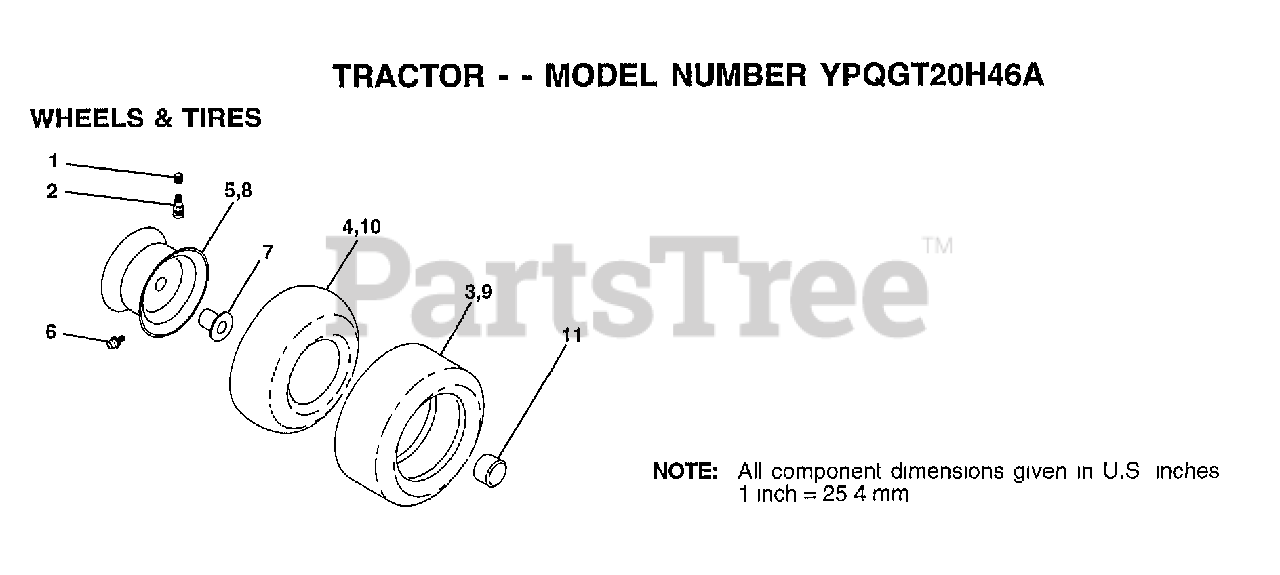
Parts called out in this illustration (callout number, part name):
1	VALVE CAP
2	VALVE STEM LT
4	TUBE.5.3/4.5/6
5	"RIM ASM 6"" FRT"
6	FITTING LT
7	"FLANGE, BEARING"
8	RIM.REAR.
10	TUBE.23X8/10-12
11	HUB CAP
